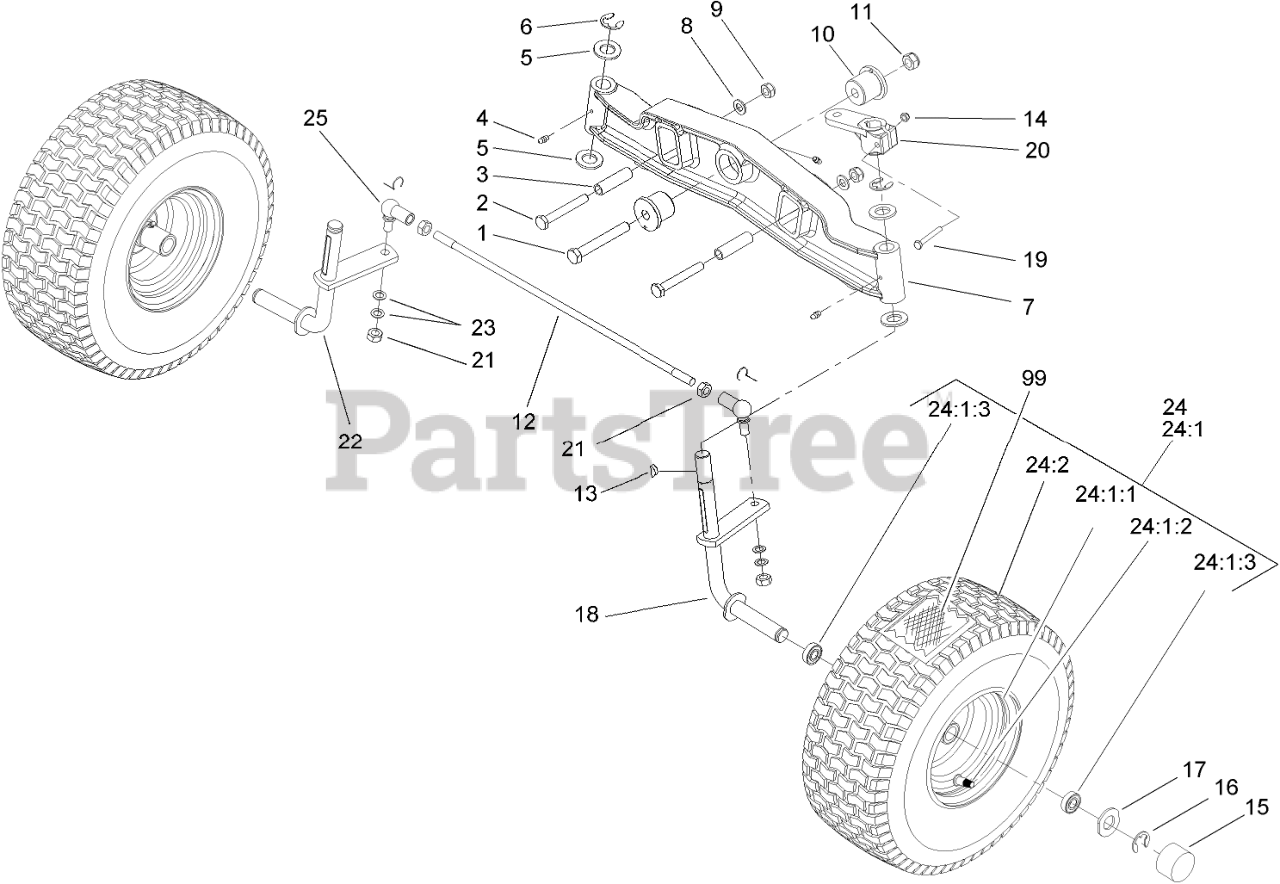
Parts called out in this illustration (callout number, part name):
1	SCREW-HH
2	SCREW-HH
3	SPACER
4	FITTING-GREASE
5	WASHER-FLAT
6	CLIP-SPRING
7	AXLE-FRONT
8	WASHER-FLAT
9	NUT-LOCK, NI
10	BUSHING-AXLE, FRONT
11	NUT-LOCKING, SELF
12	ROD-TIE, FRONT AXLE
13	KEY-WOODRUFF
14	NUT-LOCK
15	CAP-HUB
16	CLIP-SPRING
17	RETAINER-CAP, HUB
18	LH SPINDLE ASM
19	SCREW-HH
20	LEVER-SPINDLE, STEERING
21	NUT-LOCK, NI
22	RH SPINDLE ASM
23	Washer
24	WHEEL and TIRE ASM
24:1	WHEEL ASM
24:1:1	RIM
24:1:2	Valve-Tire
24:1:3	BEARING-WHEEL
25	JOINT-BALL, ANGLE
99	TUBE-INNER
